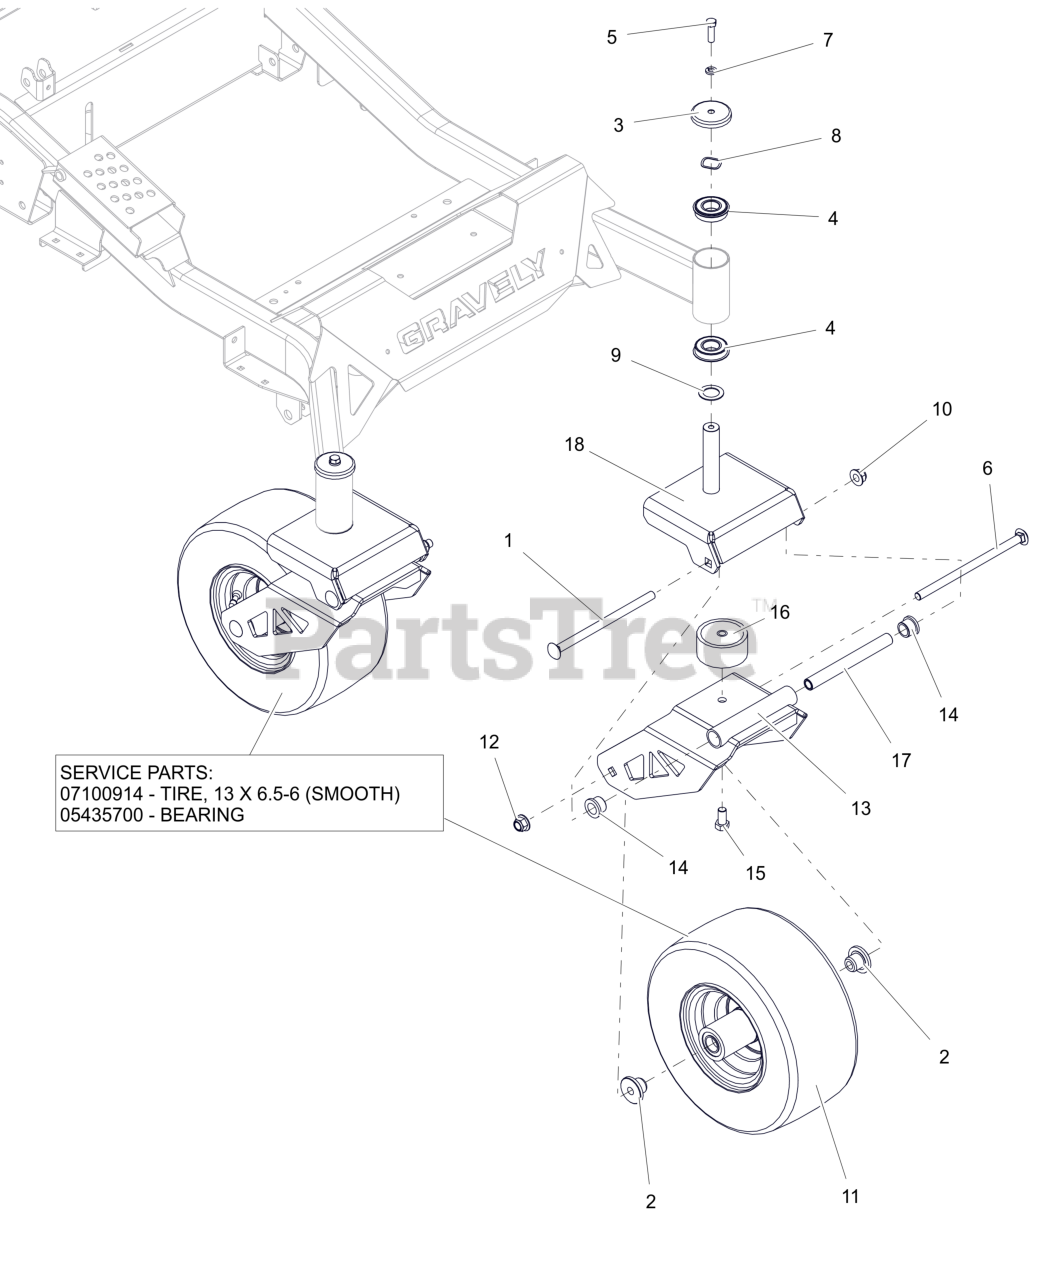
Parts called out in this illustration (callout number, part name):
1	BLT, RHSN .50-13X8.50 G5 ZCC
2	SPACER, FRONT WHEEL
3	SHIELD, AXLE BEARING
4	BEARING, BALL -2.000 OD X 1.000 ID X .5625 W/RING
5	BLT, HEX .38-16X1.25 G5 ZCC
6	BTL,RHSN .500-13 X 9 G5 ZCC
7	WSHR, LK-HVY .375X.115 ZCC
8	WSHR-WAVE 1.0X1.25X.028 .145FH
9	WSHR-HRD-THRS 1.007X1.542X.062
10	NUT,NYL-FLG .50-13 GF ZCC
11	ASM, WHL/TIRE 13X6.50-6
11	TIRE, 13X6.50-6 SMOOTH
11	BRG, 25MM ID X 52MM OD X 15MM
11	TIRE TUBE 13X6.5-6
12	NUT,NYL-FLG .50-13 GF ZCC
13	WLDMT, LOWER SUSPENSION (RED)
14	BUSHING, FLANGE .75X.75X1.0
15	BLT, HEX .50-13X1.00 G5 ZCC
16	SPCR, RUBBER SUSPENSION
17	ROD, FORK PIVOT
18	WLDMT- UPPER SUSPENSION FORK
